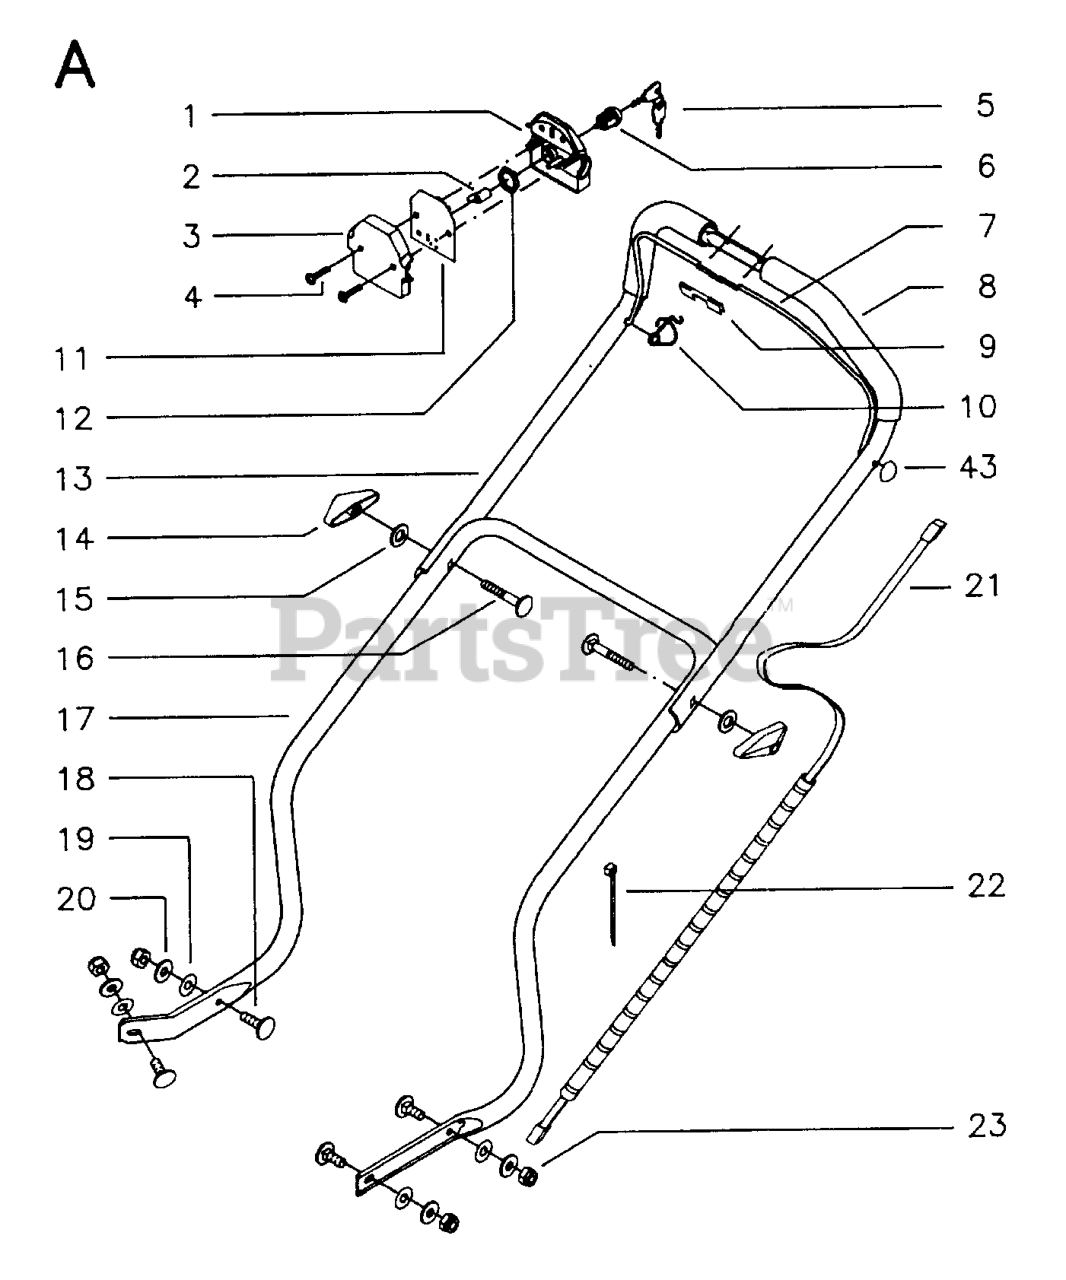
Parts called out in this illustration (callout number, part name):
8	VIBRATION DAMPENER
14	WINGNUT
15	WASHER - 15X7.3X1.6
23	LOCKNUT M6
